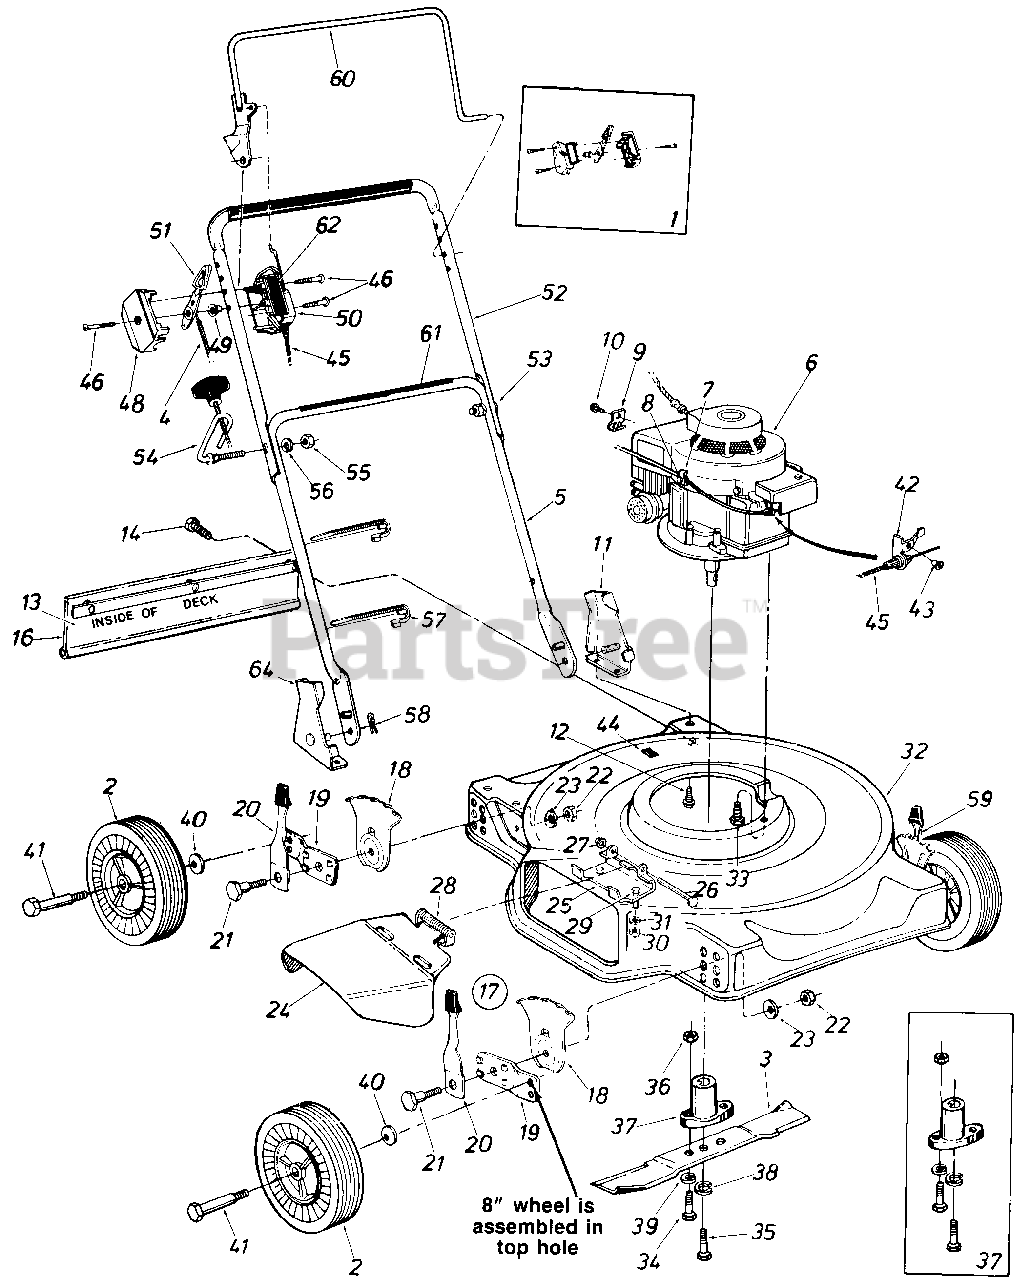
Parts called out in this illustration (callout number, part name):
1	KIT-THROTTLE CONTROL
2	WHEEL ASSY W/TIRE
3	BLADE-20IN
4	CABLE-THROTTLE
5	LOWER HANDLE
7	CLAMP-CASING
8	SCREW-HEX B-TAP #10 X .38
9	CLAMP-CONDUIT
10	SCREW-HEX WASH HD AB-TAPP #8 X .38
11	BRACKET ASSY-HDLE
12	SCREW-HEX WASH HD 5/16-18X1/2
13	STRIP-RETAINING
14	SCREW-HEX 1/4-20 C .62
16	FLAP-RR
17	ADJUSTER ASSY-HGT-RH
18	PLATE-HGT ADJ
19	BAR-PIVOT
20	LEVER & KNOB ASSY
21	SCREW-SHLD
22	NUT-HEX 3/8-16
23	WASHER-BELL
24	DEFLECTOR ASSY-CHUTE
25	PLATE-ADAPTER
26	PIN-PIVOT
28	SPRING-TORSION
29	SCREW-HEX 1/4-20 X .50
30	NUT-HEX 1/4-20
31	LOCK WASHER 1/4 DIA
34	SCREW-HEX SPECIAL 5/16-24X1.0
35	SCREW-HEX 3/8-24 X 2.25
36	NUT-5/16-24
37	KIT-BLADE ADAPTER
38	WASHER-HDL 3/8
39	WASHER-LOCK-5/16
40	WASHER-BELL .400 ID X .88 X .060
41	SCREW-SHLD .498 DIA X 1.450
42	BRACKET-CABLE
45	CABLE-CONTROL
46	SCREW-TRUSS MACH
48	PANEL HALF-CONTROL
49	PIN-CONTROL DISC
50	PANEL HALF-CLUTCH
51	LEVER-THROTTLE CONT-REV
52	HANDLE-UPPER
53	BOLT-CARRIAGE-CURV 5/16-18 X 1.38
54	SCREW-RECOIL HANDLE GUIDE
55	NUT-HEX 5/16-18
56	WASHER-LOCK-5/16
57	TIE-CABLE
58	PIN-INTERN COT-5/16 DIA
59	ADJUSTER ASSY-HGT-LH
60	HANDLE ASSY-CONTROL-RH
64	BRACKET ASSY-HDLE
